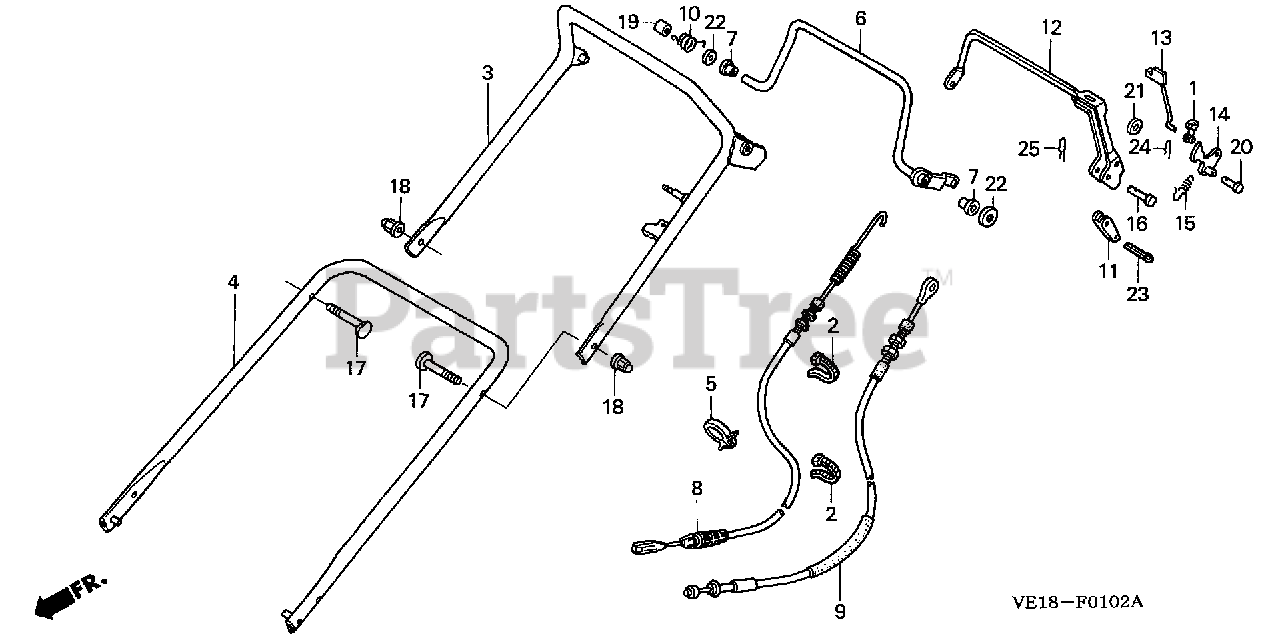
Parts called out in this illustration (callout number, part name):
1	JOINT, ROD
2	TIE, CABLE (157.5MM)
3	PIPE, HANDLE (UPPER) *NH105* (MAT BLACK)
4	HANDLE (LOWER) *NH105* (MAT BLACK)
5	CLIP, POWER STEERING SUCTION TUBE
6	LEVER, CLUTCH
7	BUSH, CLUTCH LEVER
8	CABLE, CLUTCH
9	CABLE, ROTO-STOP
10	SPRING, R. STOP RETURN
11	ARM, ROTO-STOP CABLE
12	LEVER, ROTO-STOP
13	ROD, RATCHET PUSH
14	LEVER, LOCK
15	SPRING, RATCHET RETURN
16	PIN, CLUTCH LEVER
17	BOLT, HANDLE HOLDER (8X36)
18	NUT, CAP (8MM)
19	COLLAR (8X11X13.5)
20	PIN, LOCK LEVER HINGE (6X30)
21	WASHER, PLAIN (6MM)
22	WASHER, PLAIN (8MM)
23	PIN, SPLIT (2.0)
24	PIN, LOCK (6MM)
25	PIN, LOCK (8MM)
